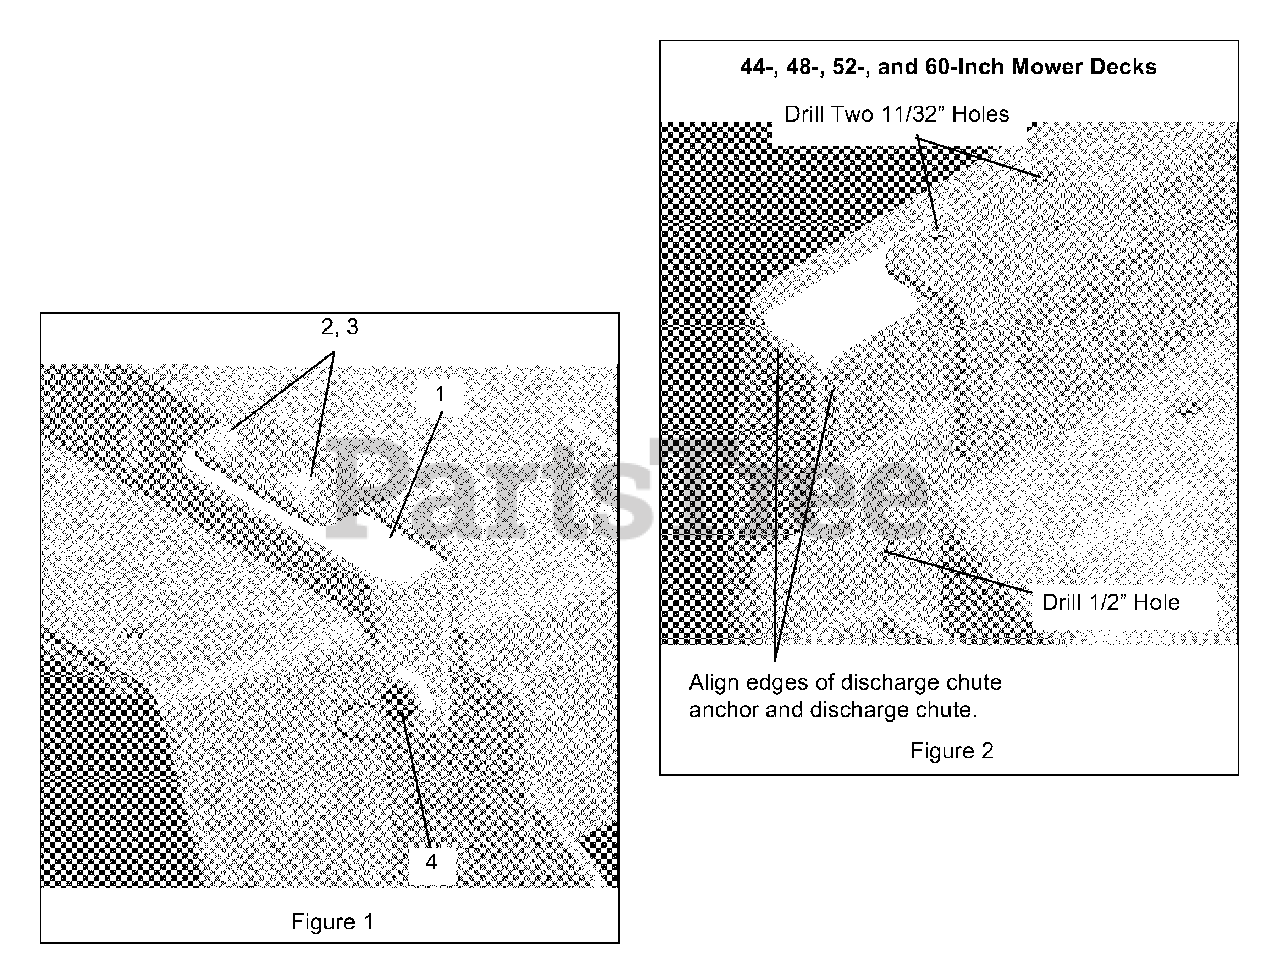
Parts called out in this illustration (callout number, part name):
1	WMT - DISCHARGE CHUTE ANCHOR
2	@BLT-HEX .31-18X.75 GR5 YWZC
3	@NUT-LK-TOP-FLG .31-18 YWZC
4	PULL PIN,.50-13THDX.310 PLNGR
